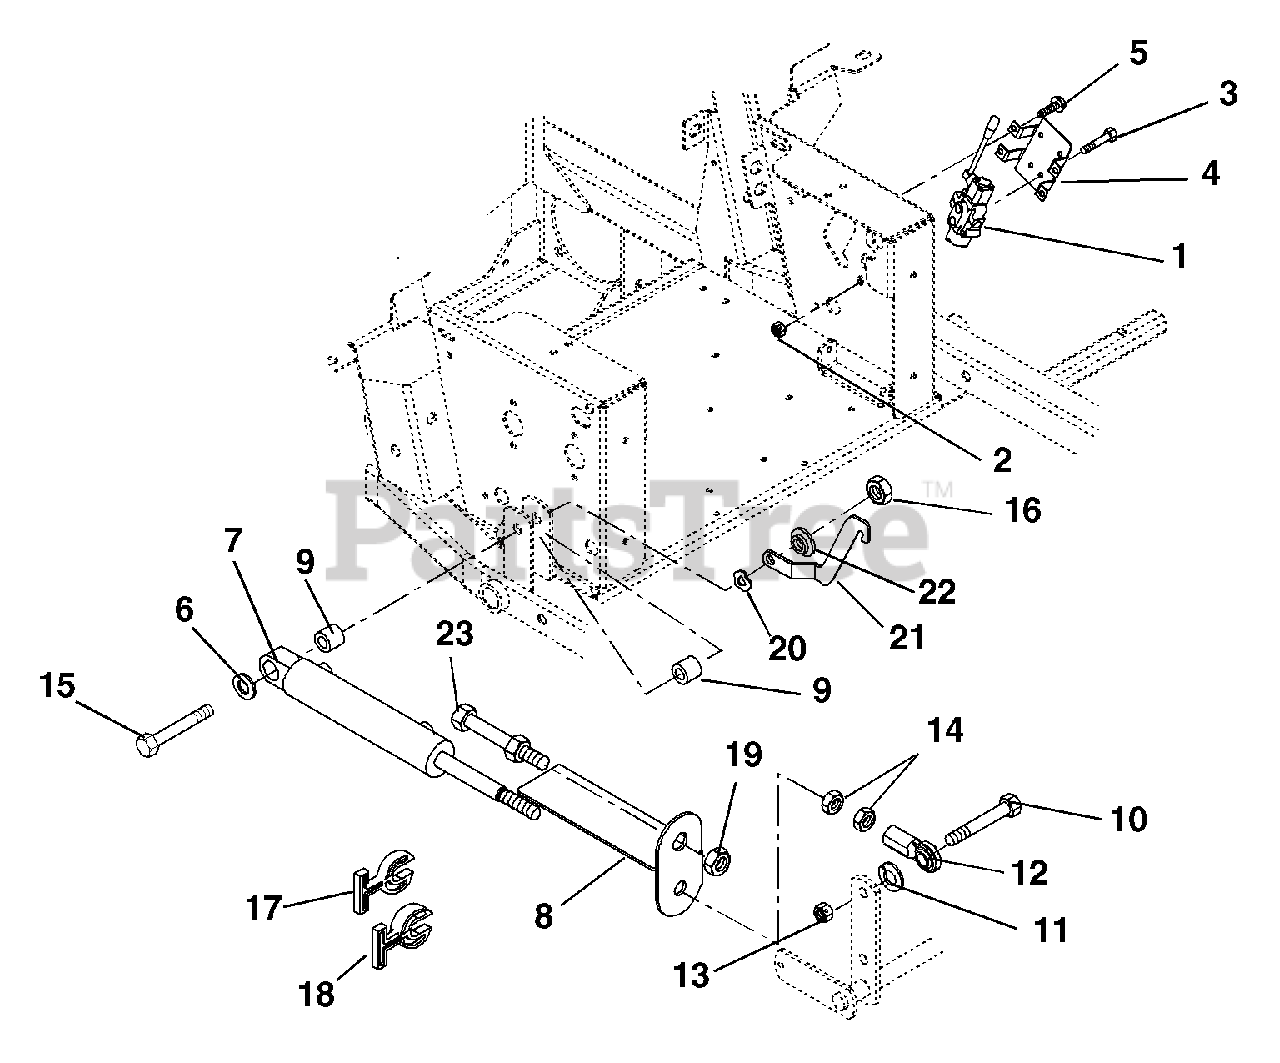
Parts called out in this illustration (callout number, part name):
1	VALVE, HYDRAULIC-BONDIOLI
2	@NUT-LK-TOP-FLG .31-18 YWZC
3	@BLT-HEX .31-18X2.25 GR5 YWZC
4	VALVE MOUNTING BRACKET - BLACK
5	@SCR-TAP .38-16X.50 HWH TR YWZ
6	WSHR-FL-STL .515X1.625X.250 YZ
7	CYLINDER - HYDRAULIC LIFT
8	STRAP, CUT INDICATOR/GUARD
9	BUSHING, .516X1.000X1.050 LG
10	BLT-HEX .62-11X2.25 YWZC GR8
11	@WSHR-LK .62X.156 REG YWZC
12	ROD END, 5/8 RH - FEMALE
13	@NUT-LK-CTR .62-11 YWZC
14	NUT-JAM .625-18 YWZC
15	@BLT-HEX .50-13X3.75 GR5 YWZC
16	@NUT-LK-TOP-FLG .50-13 YWZC
17	STOP, CYLINDER .34 THK
18	STOP, CYLINDER .680 THK
19	NUT-JAM CTRLK .75-16 YWZC
20	WASHER-WAVE .760X1.120X.080
21	LATCH, FLOOR BOARD (L/C)
22	BSHG-FLG .515X.750X.285X1.120
